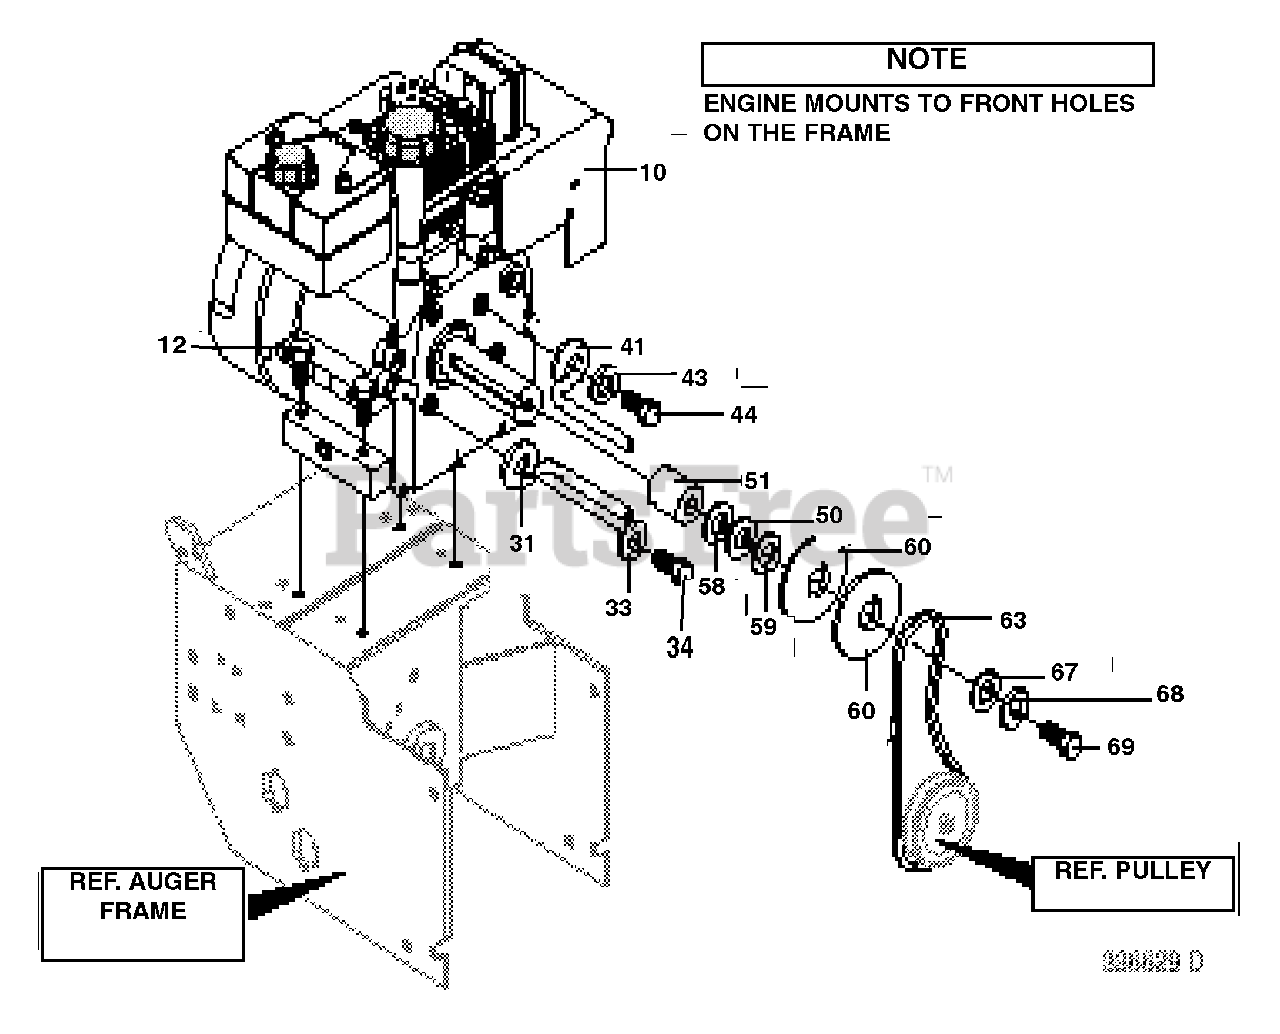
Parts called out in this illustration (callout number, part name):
10	Engine
12	Screw, 5/16-18
31	Guide, Rod Belt, RH
33	Washer, .328 x .60 x .09
34	Screw, 5/16-24 x .625
41	Guide, Rod Belt RH
43	Washer, .328 x .60 x .09
44	Screw, 5/16-24 x .625
51	Spacer, Slev .75 x 1.25 x 1.32
58	Flatwasher .765 x 1.12 x .06
59	Spacer, Slev .753 x 1.12 x .38
60	Pulley, Eng V4L 3.00 x .75
63	Belt, V 4L 35.23 Lg.
67	Flatwasher
68	Washer, Regsptlk
69	Screw, 3/8-24 x 1.00
